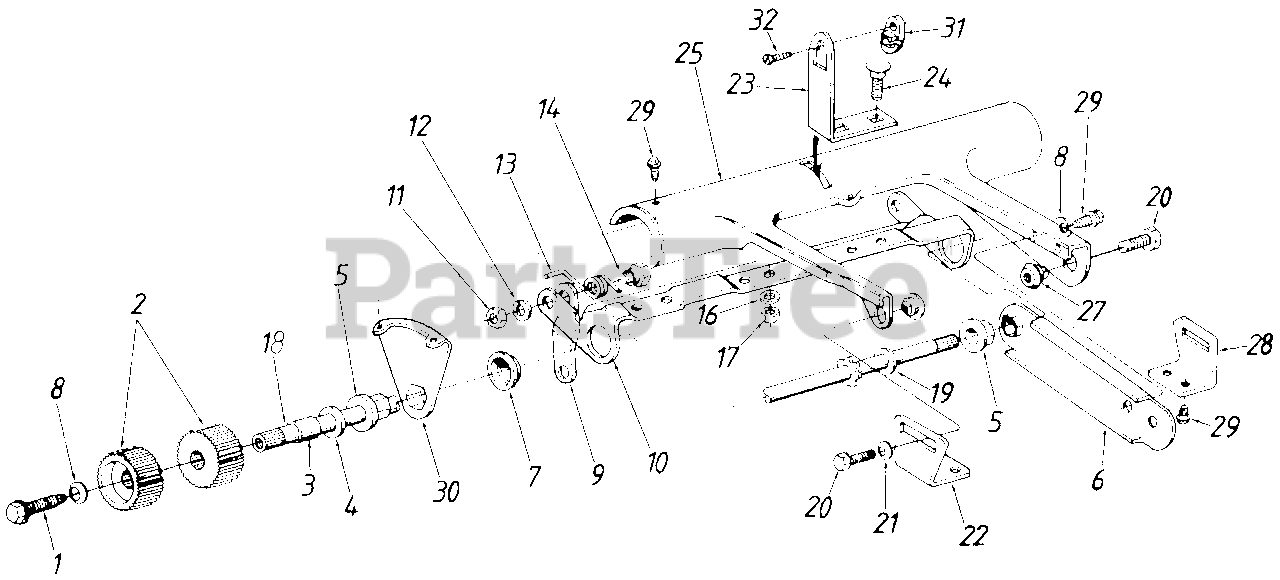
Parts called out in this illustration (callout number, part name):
1	Hex Wash. Hd. Tap Scr. 1/4-20 x .75" Lg.
2	Wheel Drive Pinion-Half
3	Sleeve .526" I.D. x .69" O.D.
4	Fl-Wash. .51" I.D. x .75" O.D.
5	Hex Flange Brg. .504" I.D.
8	Bell-Wash. .265" I.D. x .75"
11	Hex Nut 5/16-18 Thd.
12	L-Wash. 5/16" I.D.
13	Torsion Spring-R.H.
14	Shoulder Bolt .437" Dia.
16	L-Wash. 1/4" I.D.
17	Hex Nut 1/4-20 Thd.*
18	Drive Shaft Ass'y.
19	Fl-Wash. .531" I.D. x .93"
20	Hex Bolt 5/16-18 x .625" Lg.
21	Bell-Wash. .345" I.D. x .88"
22	Pivot Bracket-R.H.
28	Pivot Bracket-L.H.
29	Hex Wash. Hd. AB-Tap Scr. 1/4 x .62" Lg.
32	Hex B-Tap Scr. #10 x .44"
